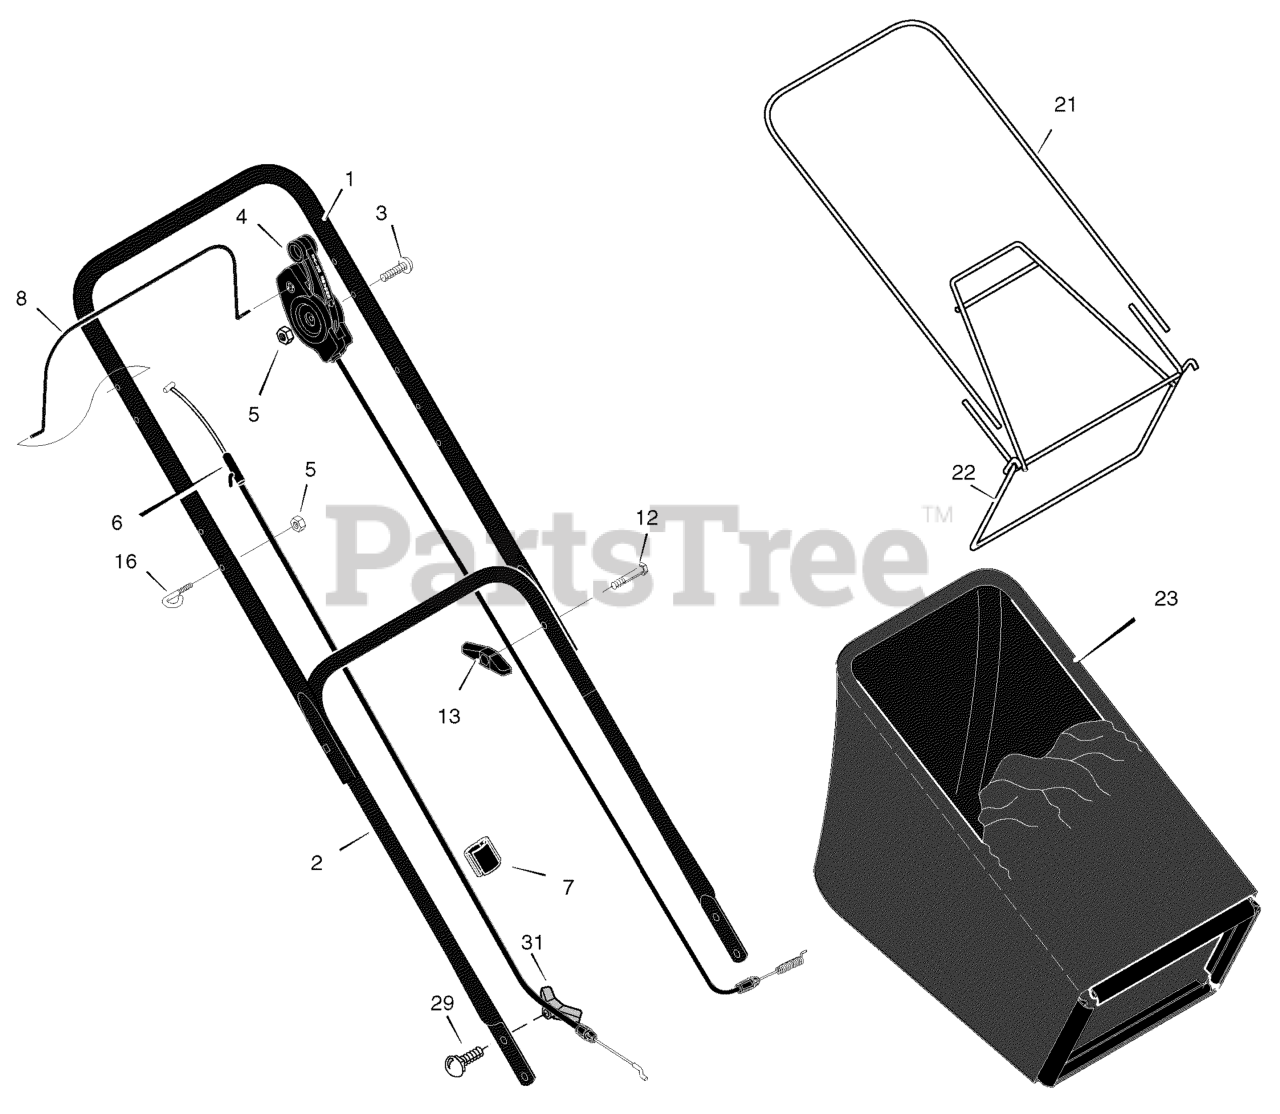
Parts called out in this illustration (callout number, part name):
1	Handle, Upper (Black)
1	Handle, Upper (Gray)
2	Handle, Lower (Black)
2	Handle, Lower (Gray)
4	Control, Drive
5	Locknut
6	Cable, Stop
7	Fastener, Cable
8	Lever, Stop
16	Guide, Rope
21	Frame, Top
22	Frame Assembly
23	Bag, Cloth
29	Bolt, Carriage
31	Knob, Plastic
